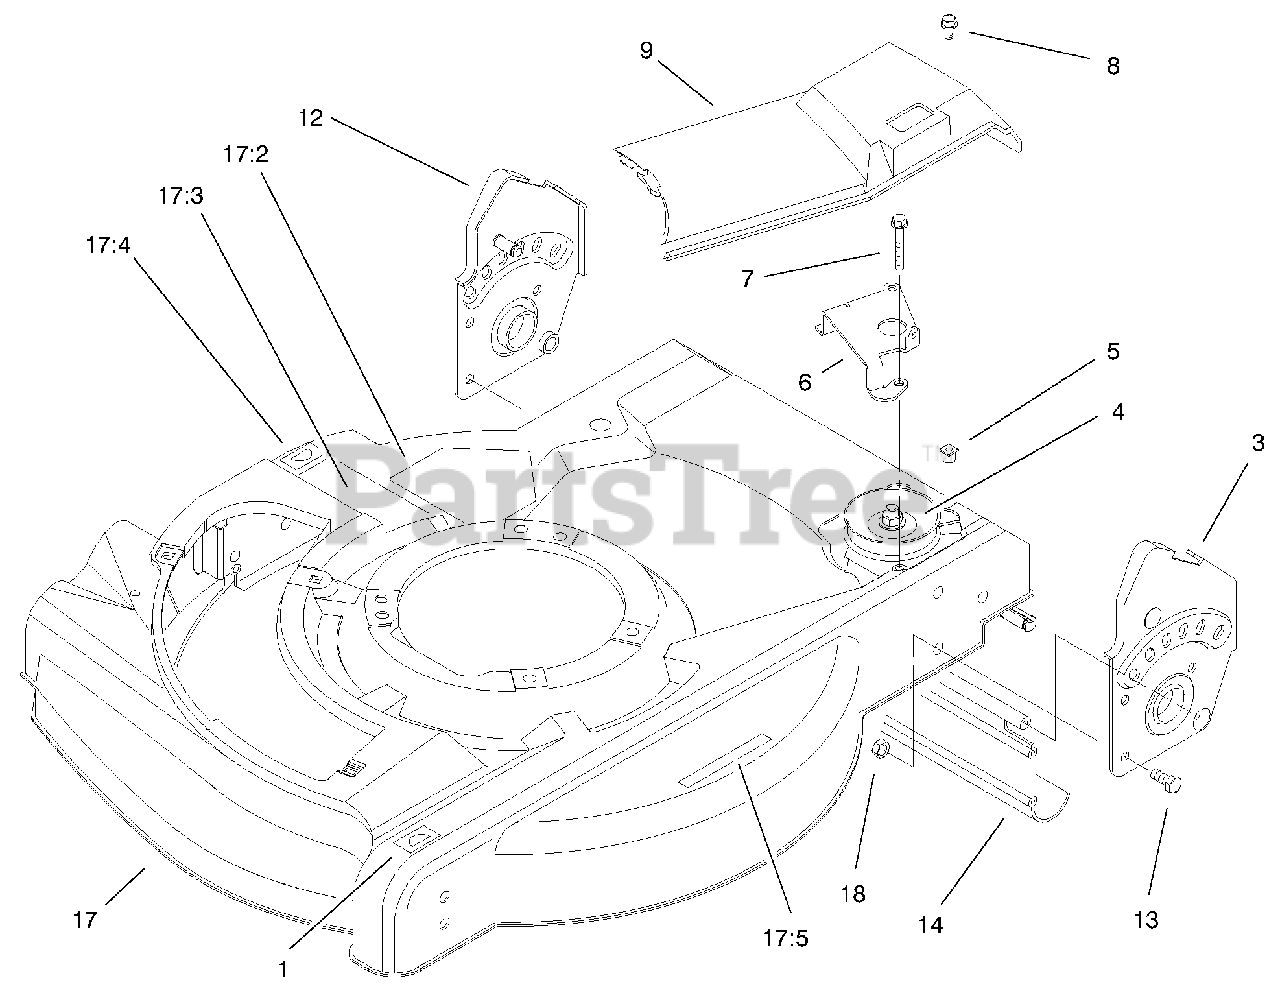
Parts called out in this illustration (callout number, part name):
1	Decal-HOC
3	ASM-Handle Bracket
4	ASM-Gear Case
5	Grommet
6	Guide-Transmission
7	Screw-Thread Forming
8	Screw-Phil
9	Cover-Drive
12	ASM-Handle Bracket
13	Screw-HH
14	Shield-Trailing
17	ASM-Housing & Baffle
17:2	Decal-Danger
17:3	Decal-Discharge
17:4	Decal-HOC
17:5	Decal-Warning
18	Nut-Lock
